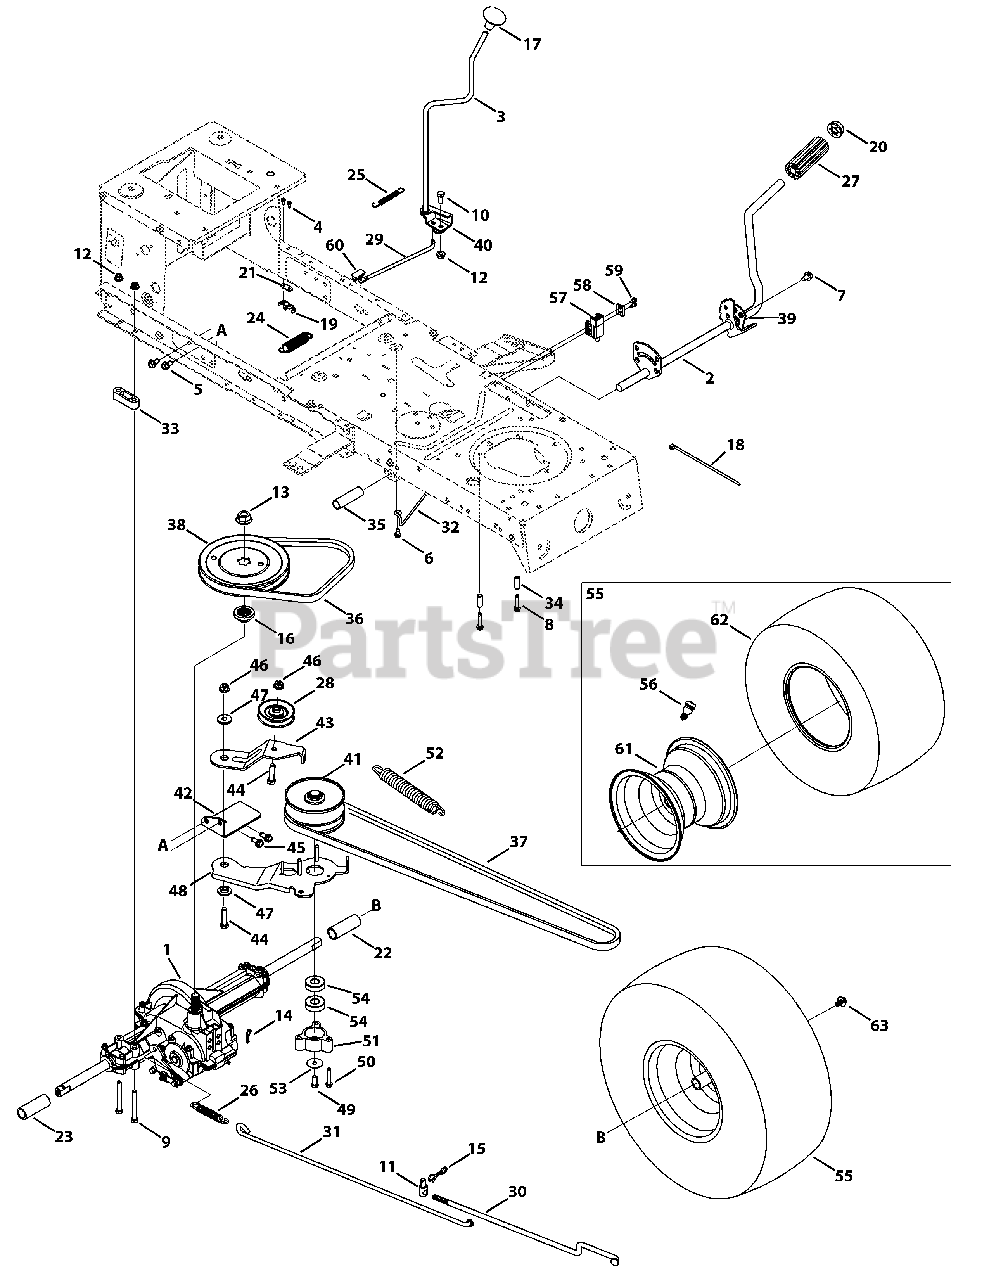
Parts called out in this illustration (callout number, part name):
1	Transmission Drive Assembly
2	Pedal Assembly
3	Shaft Lever Assembly
4	Screw, 8-18:0.500
5	Screw, 5/16-18 x .750
6	Screw, 1/4-20 x 0.500
7	Screw, 5/16-18 x 0.625
8	Screw, 1/4-20 x 1.250
9	Hex Screw, 5/16-18 x 3.50
9	Hex Screw, 5/16-18 x 2.75
10	Hex Screw, 5/16-18 x .75
11	Ferrule, 3/8-24 X .375 DIA.
12	Flangelock Nut, 5/16-18
13	Flange Nut, 9/16-18
14	Cotter Pin INT- .125 DIA
15	Bow-Tie Cotter Pin, 72
16	Pulley Hub, 5/8 SPLINE
17	Shift Knob
18	Cable Tie
19	Short Spring Switch
20	Push Cap, 5/8
21	Plate Insulator Nut
22	Sleeve, .758 x .821 x 3.3125
23	Sleeve, .758 x .821 x 2.4375
24	Spring Extension, .80 OD x 3.28 LG
25	Spring Extension, .38 OD x 3.25 LG
26	Spring Extension, .59 OD x 4.00 LG
27	Foot Pad, 4.0 LONG
28	Idler Pulley
29	Shift Rod, 38" & 42"
30	Variable Speed Control Rod
31	Brake Rod
32	Belt Keeper Rod
33	Spacer, T-Axle, 42" Only
34	Spacer, .260 x .375 x 1.030 LG
35	Spacer, .640 ID x .76 OD x 2.63
36	V Belt, 5L 35.25 POLY, 38" & 42"
37	V Belt, 5L 70.90 POLY
38	V Pulley 7.25 DIA SPUN, 38" & 42"
39	Pedal Support Bracket
40	Shaft Adjust Bracket
41	Variable Speed Pulley Assembly
42	Transmission Bracket Assembly
43	Idler Bracket Assembly
44	Hex Screw, 3/8-16 x 1.75
45	Screw, 5/16-18 x 0.750
46	Flangelock Nut, 3/8-16
47	Shoulder Spacer, .625 ID x .169
48	Bracket Assembly
49	Hex Screw, 5/16-24 x .750
50	Screw, 1/4-20 x 1.500
51	Bearing Cup
52	Extension Spring, .94 OD x 6.75 LG
53	Flat Washer, .330 x 1.25 x .06:HT
54	Ball Bearing, 17 x 40 x 12
55	Wheel, 20 x 8 x 8, 42" Sq. Tred
56	Valve, tubeless Air
57	Switch Interlock
58	Plate Switch
59	Shoulder Screw, #10-32 x .500
60	Shift Plate Bearing
61	Rim, 8.0 x 7.0 x .750, 42"
62	Tire, 20 X 8 X 8 Sq Shldr, 42
63	Screw, 5/16-24 x .750
